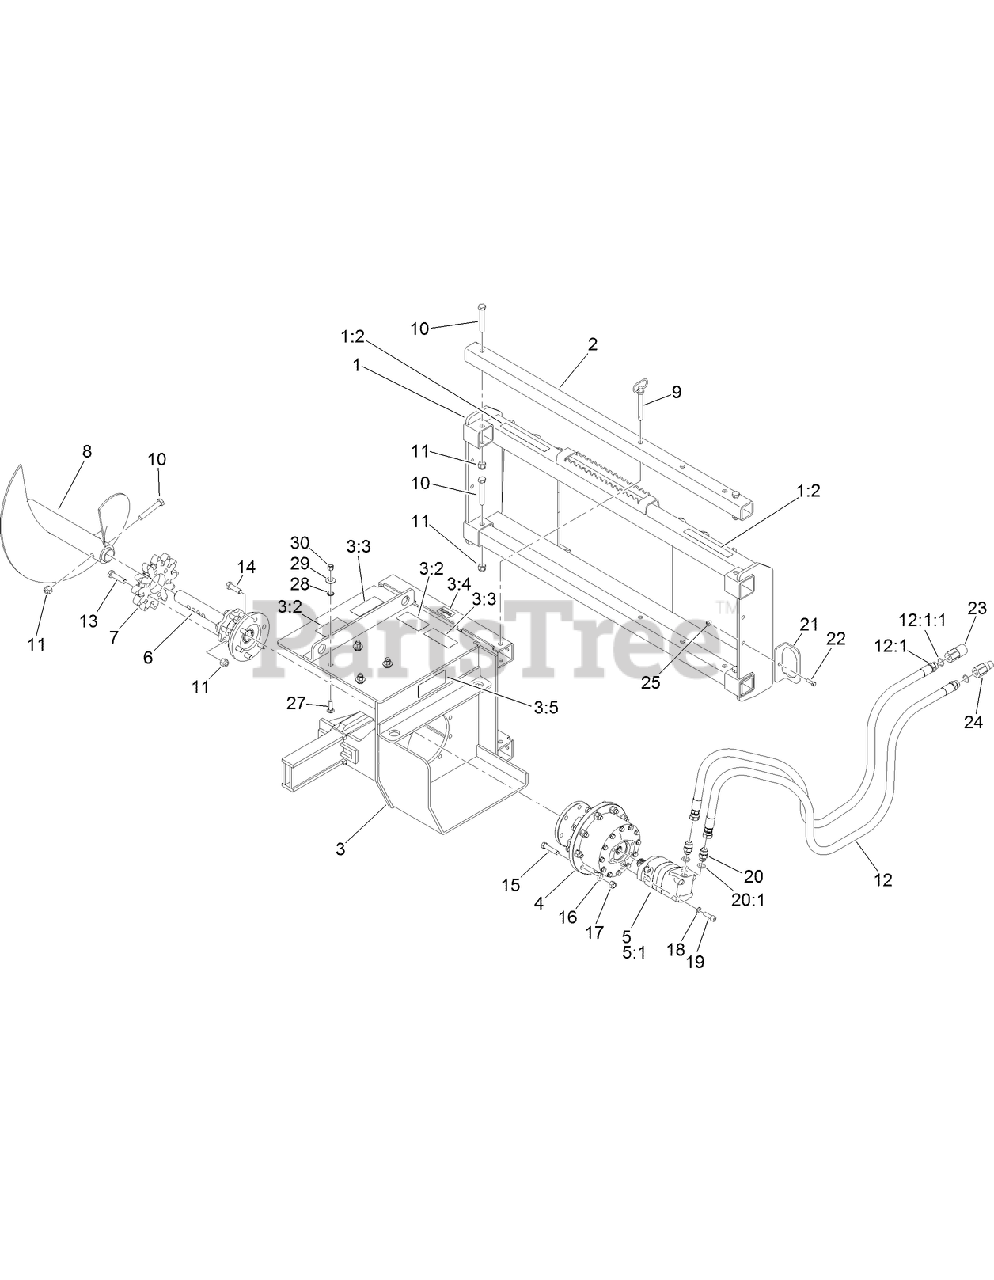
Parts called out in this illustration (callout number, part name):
1	FRAME ASM
1:2	DECAL-DANGER
2	TUBE-ADJUSTMENT
3	HEAD FRAME ASM
3:2	DECAL-WARNING, PINCH POINT
3:3	DECAL-DANGER
3:4	DECAL
3:5	DECAL-WARNING
4	PLANETARY ASM
5	HYD MOTOR ASM
5:1	SEAL KIT
6	SHAFT-DRIVE
7	SPROCKET-DRIVE
8	AUGER-SPOIL
9	PIN-HITCH
10	SCREW-HHCS
11	NUT-LOCK, NI
12	HOSE ASM
12:1	FITTING-STRAIGHT
12:1:1	O-RING
13	SCREW-HH
14	SCREW-HH
15	SCREW-HH
16	WASHER-LOCK
17	NUT-LOCK
18	SCREW-HH
19	SCREW-HSH
20	FITTING-STRAIGHT
20:1	O-RING
21	GUIDE-HOSE
22	SCREW-HH
23	FITTING-ADAPTER
24	FITTING-ADAPTER
25	NUT-HF, NI
27	SCREW-CARR
28	NUT-PUSH
29	WASHER-FLAT
30	NUT-LOCK, NI
